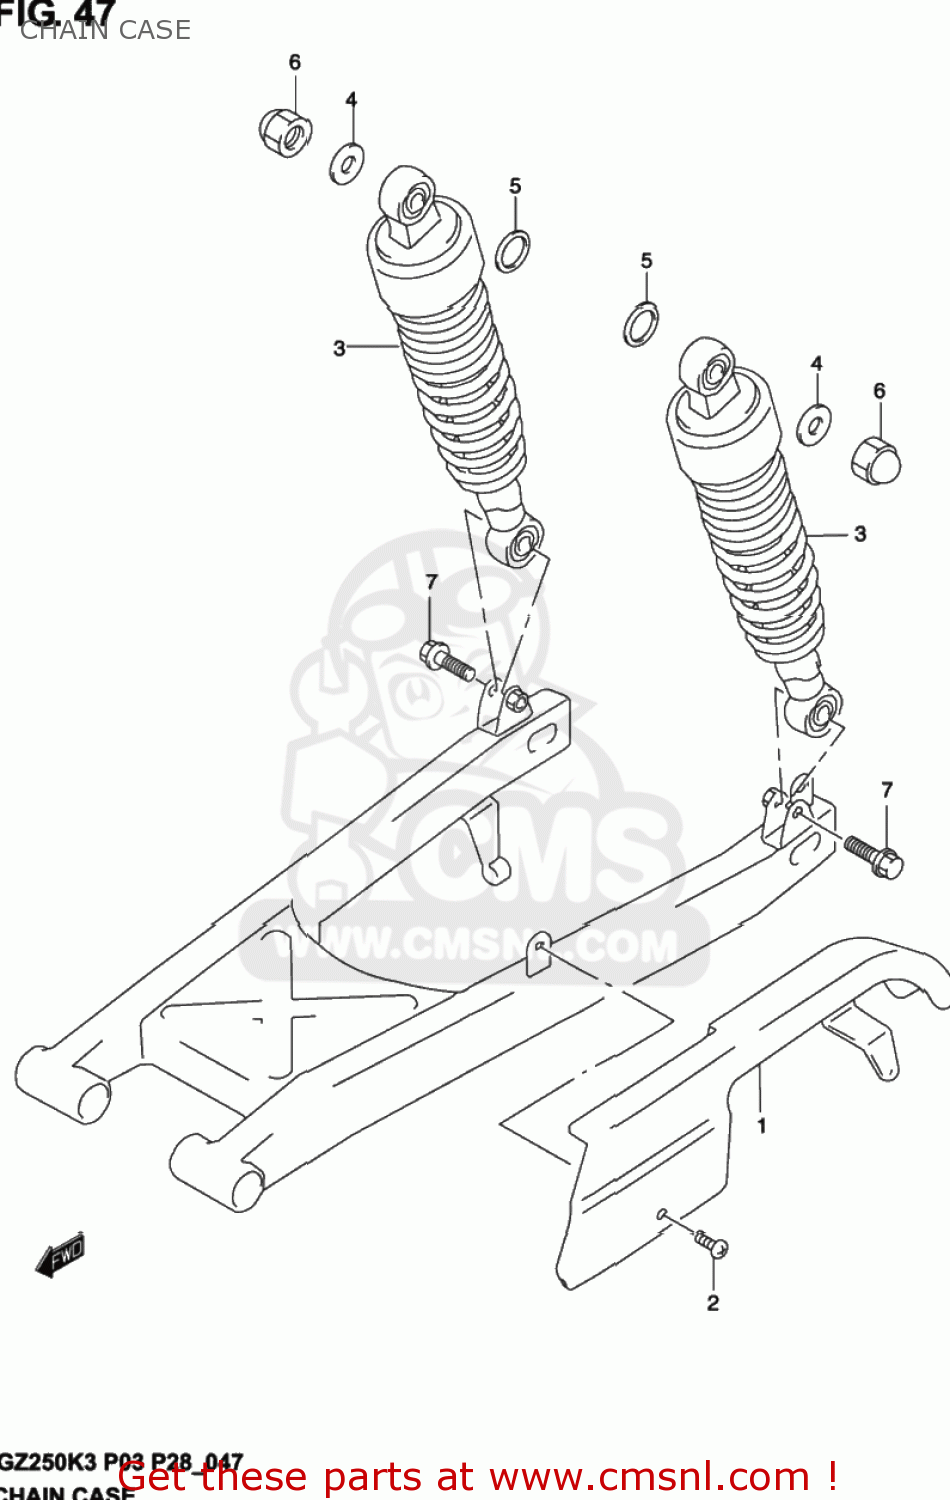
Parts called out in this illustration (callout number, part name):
1	CASE, CHAIN
2	SCREW 6X10
3	ABSORBER ASSY,RR SHOCK
4	WASHER (10.5X24X2.3)
5	WASHER
6	NUT
7	BOLT(10X37)
